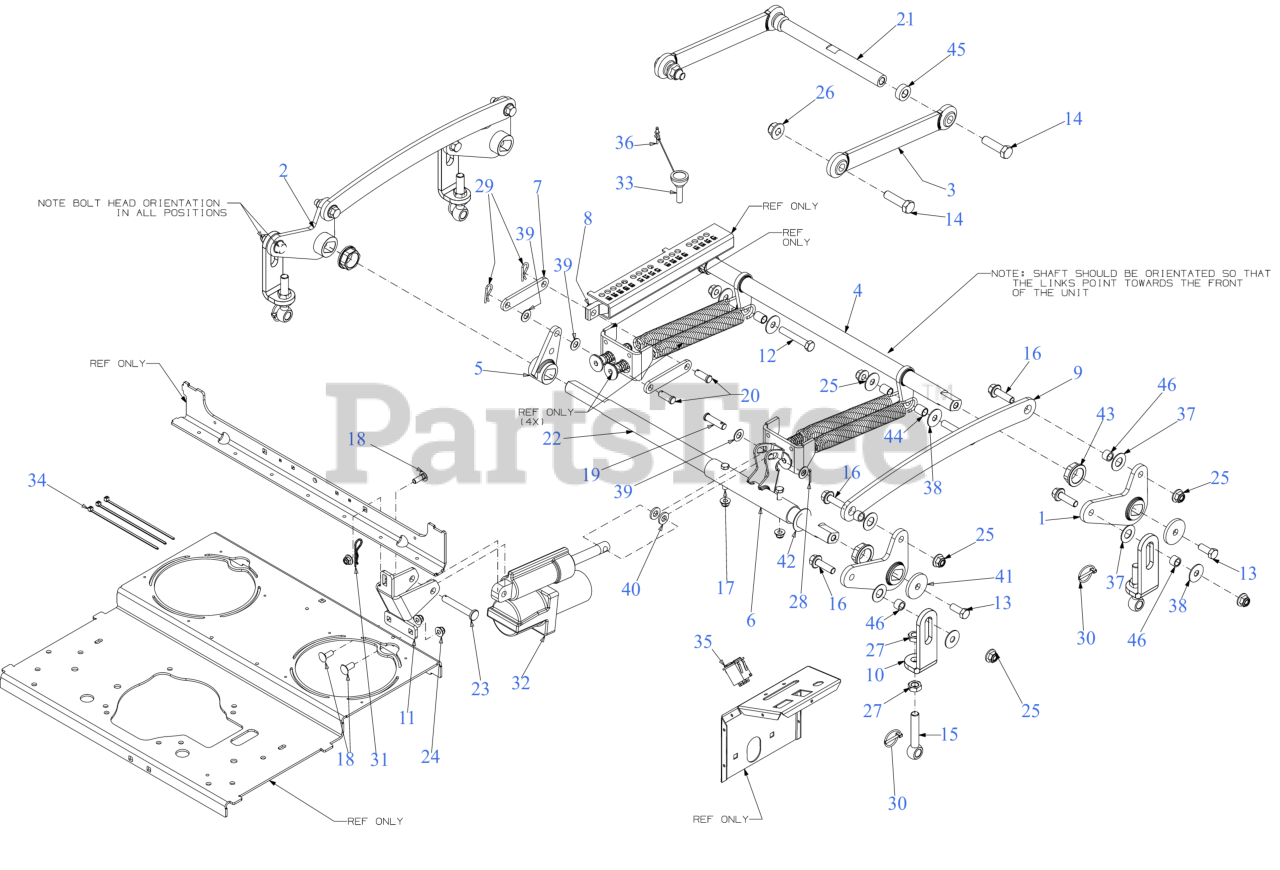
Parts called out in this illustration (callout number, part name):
4	FRONT DECK LIFT SHAFT
5	DECK LIFT HUB ASSEMBLY (LH)
6	LIFT BRACKET
7	DECK LIFT INDEX LINK
8	LIFT INDEX SLIDER ARM
11	LIFT CYLINDER BRACKET
12	SCREW-HEX 1/2-13 x 3.00
13	SCREW 1/2-13 x 1.25 GR5
14	SCREW 5/8-11 x 2.25 GR5
15	EYE BOLT 5/8-11 x 3.63
16	FLANGE BOLT 1/2-13:1.75:GR5
17	SCREW 3/8-16 x 2.0 GR5
18	CARRIAGE BOLT 3/8-16 x 1.00 GR5
19	CLEVIS PIN .500 x 1.875
20	CLEVIS PIN .500 x 1.25
21	FRONT LIFT SHAFT
22	LIFT SHAFT 1.25 DIA
23	CLEVIS PIN .50"OD
26	FLANGE LOCK NUT
28	COTTER PIN-1/8 D
29	COTTER PIN
30	LYNCH PIN .1875
31	COTTER PIN .125X2.
32	ELEC/HYD LIFT CYLINDER
33	DECK LIFT KNOB
34	7" CABLE TIE
35	DECK LIFT SWITCH
36	FULL TUBULAR RIVET
37	FLAT WASHER .760ID X1.49OD x .06
38	WASHER .51 x 1.5 x .07
39	FLAT WASHER .510 x .995
40	FLAT WASHER .510 x 1.000 x .125
41	FLAT WASHER .53"x2.125"x.25"
42	THRUST WASHER 1.25X1.94X.063 7000
43	FLANGE BEARING
44	SPACER 0.535 x 0.68 x 0.83
45	SPACER .635X1.25X.445
